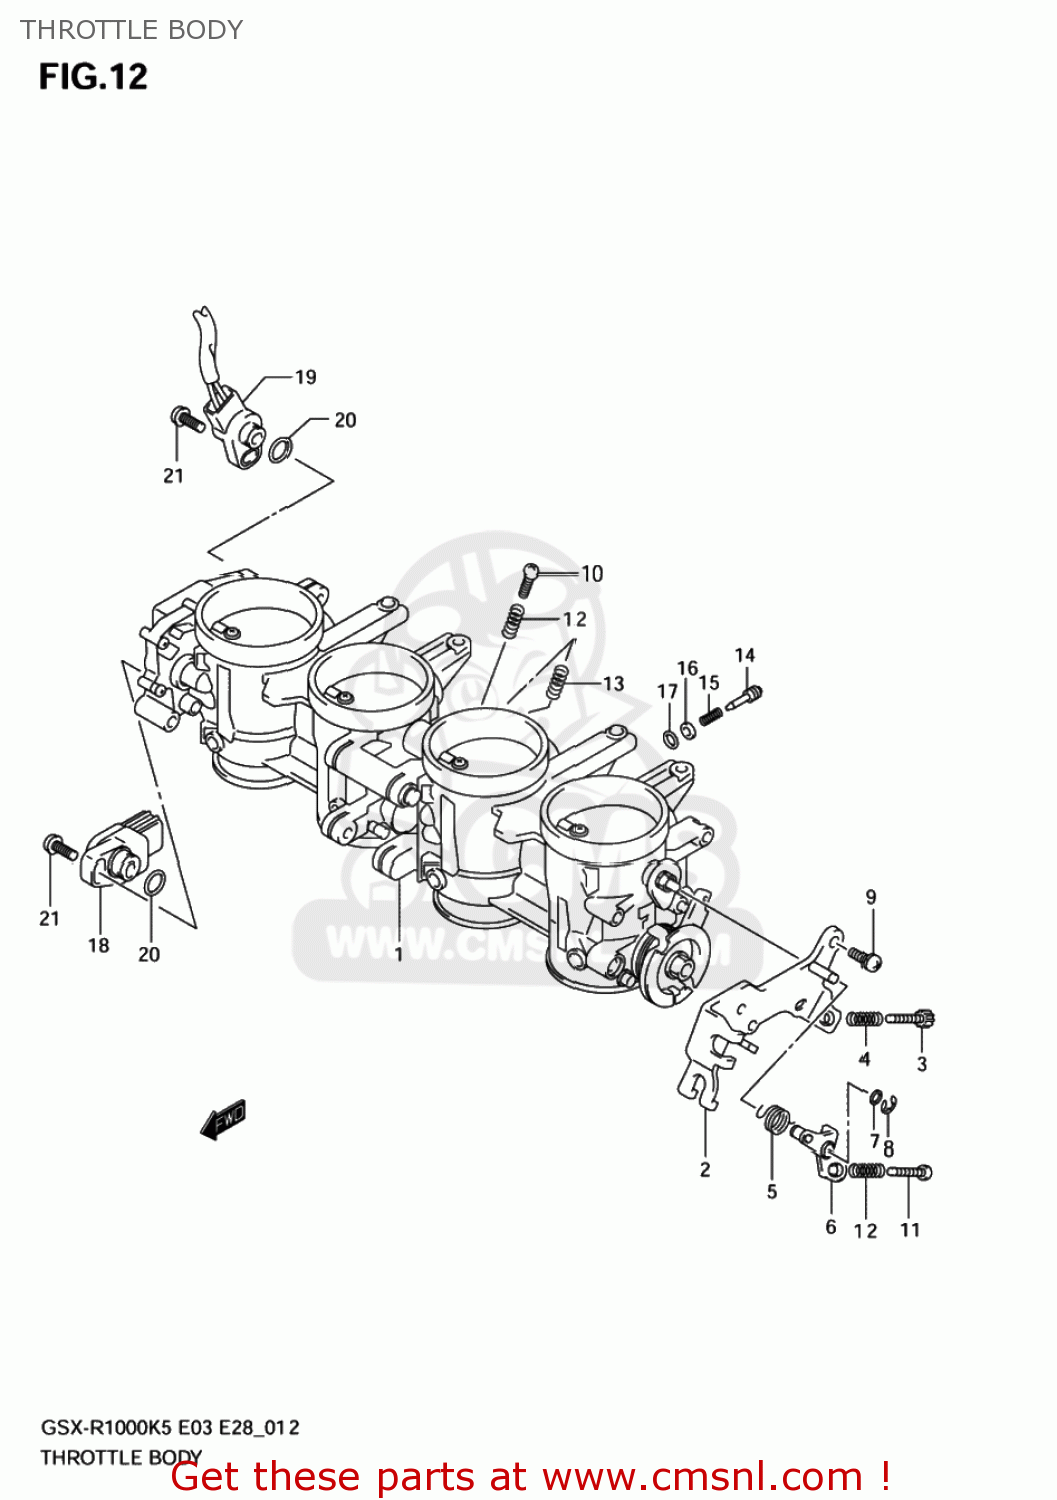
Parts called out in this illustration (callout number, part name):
1	BODY ASSY,THROTTLE
2	PLATE,STAY
3	SCREW,STOP
4	SPRING
5	SPRING
6	LEVER,LINK
7	WASHER
8	E CLIP
9	SCREW
10	SCREW,STOP
11	SCREW
12	SPRING
13	SPRING
14	SCREW,AIR ADJUST
15	SPRING
16	WASHER
17	O RING
18	SENSOR ASSY,THROTTLE MAIN
19	SENSOR ASSY,TH
20	O RING
21	SCREW
